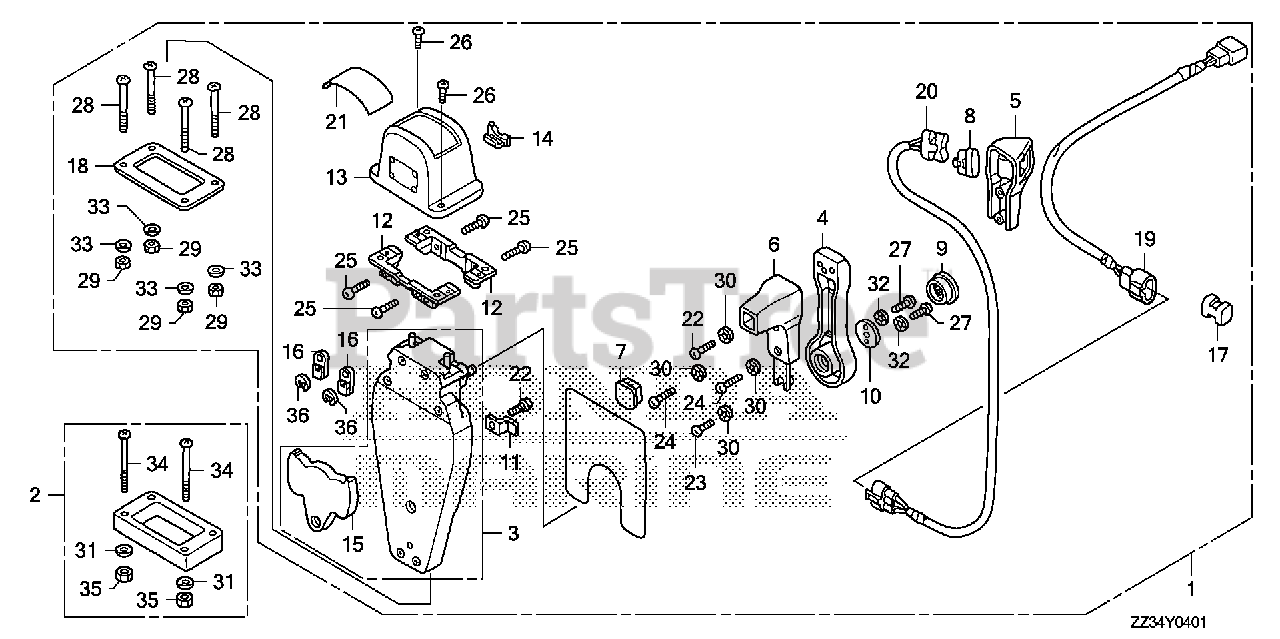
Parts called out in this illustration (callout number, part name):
1	BOX KIT, REMOTE CONTROL (TOP MOUNT SINGLE)(L)
2	SPACER KIT, REMOTE CONTROL BOX (TOP MOUNT SINGLE)
3	HOUSING ASSY., R. (INNER) (TOP MOUNT)
4	HANDLE, REMOTE CONTROL
5	COVER, R. GRIP
6	GRIP, REMOTE CONTROL HANDLE
7	CAP, GRIP
8	CAP, SWITCH
9	BUTTON, THROTTLE
10	PLATE, HANDLE
11	PLATE, CABLE CLAMP
12	BRACKET, REMOTE CONTROL HOUSING
13	HOUSING, REMOTE CONTROL BOX
14	HOUSING, LEAD
15	PLATE, DWELL
16	TERMINAL, CABLE
17	SPACER, CABLE CLAMP
18	GASKET, SINGLE
19	SUB-HARNESS ASSY., POWER TRIM-TILT (B)
20	SWITCH ASSY., POWER TRIM-TILT (B)
21	MARK, REMOTE CONTROL (SINGLE)
22	SCREW, PAN (5X16)
23	SCREW, PAN (5X10)
24	SCREW, PAN (5X20)
25	SCREW, PAN (5X18)
26	SCREW, PAN (4X10)
27	SCREW, PAN (6X18)
28	SCREW, PAN (5X40)
29	NUT, HEX. (5MM)
30	WASHER, LOCK (5MM)
31	WASHER, PLAIN (5MM)
32	WASHER, LOCK (6MM)
33	WASHER, PLAIN (5MM)
34	SCREW, PAN (5X65)
35	NUT, HEX. (5MM)
36	E-RING (6MM)
